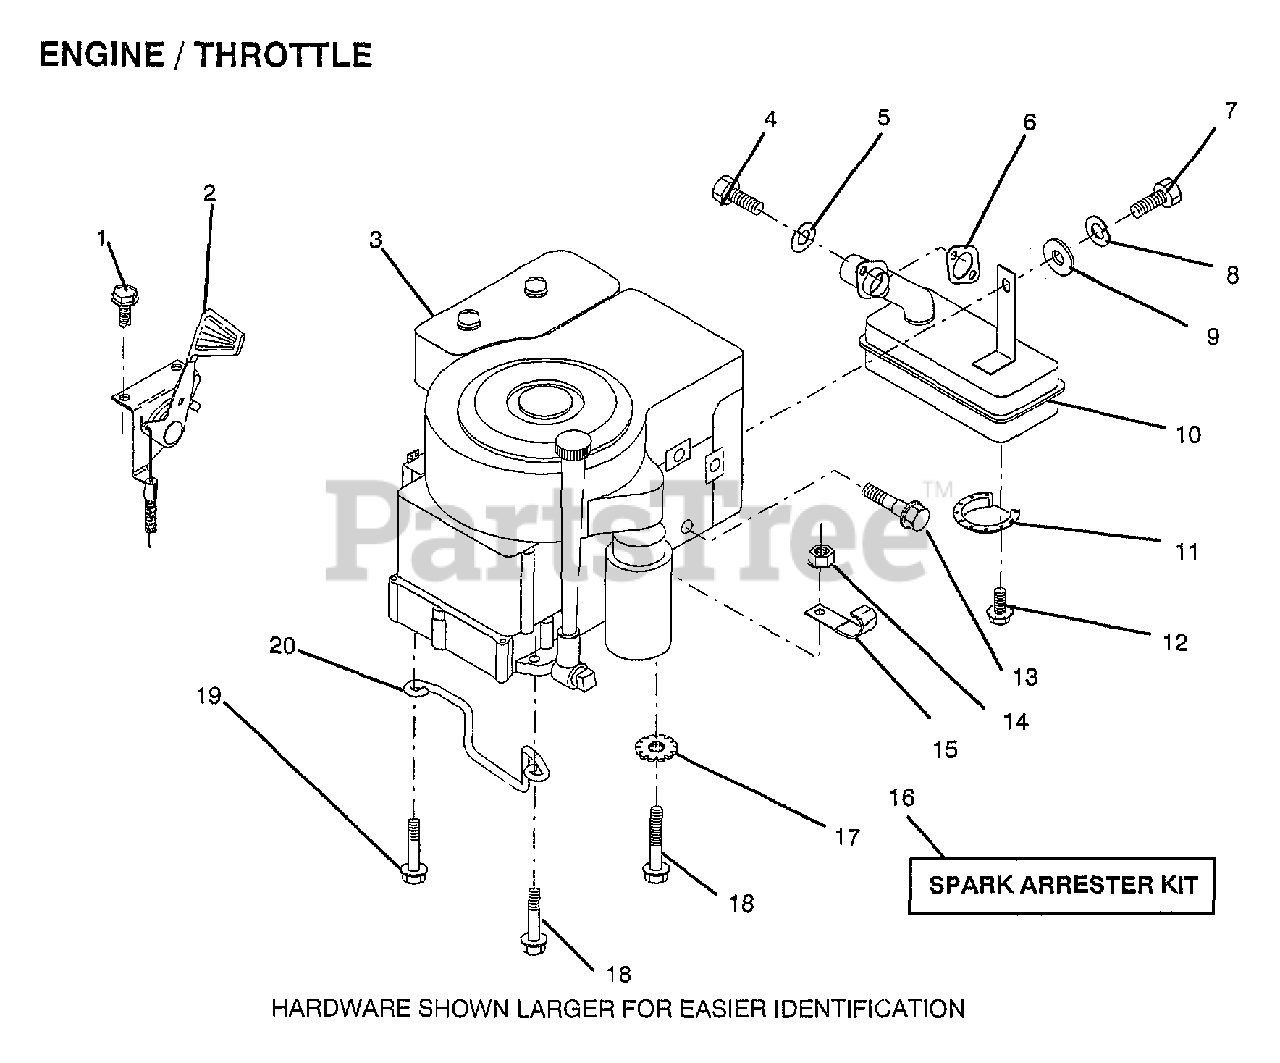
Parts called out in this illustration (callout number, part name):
1	SCREW
4	SCREW
5	LOCKWASHER
8	LOCKWASHER
11	DEFLECTOR.222573
13	BOLT T
14	NUT
15	CLIP T
17	LOCKWASHER
18	SCREW LT
19	SCREW LT
20	"KEEPER,DR BELT GR"
